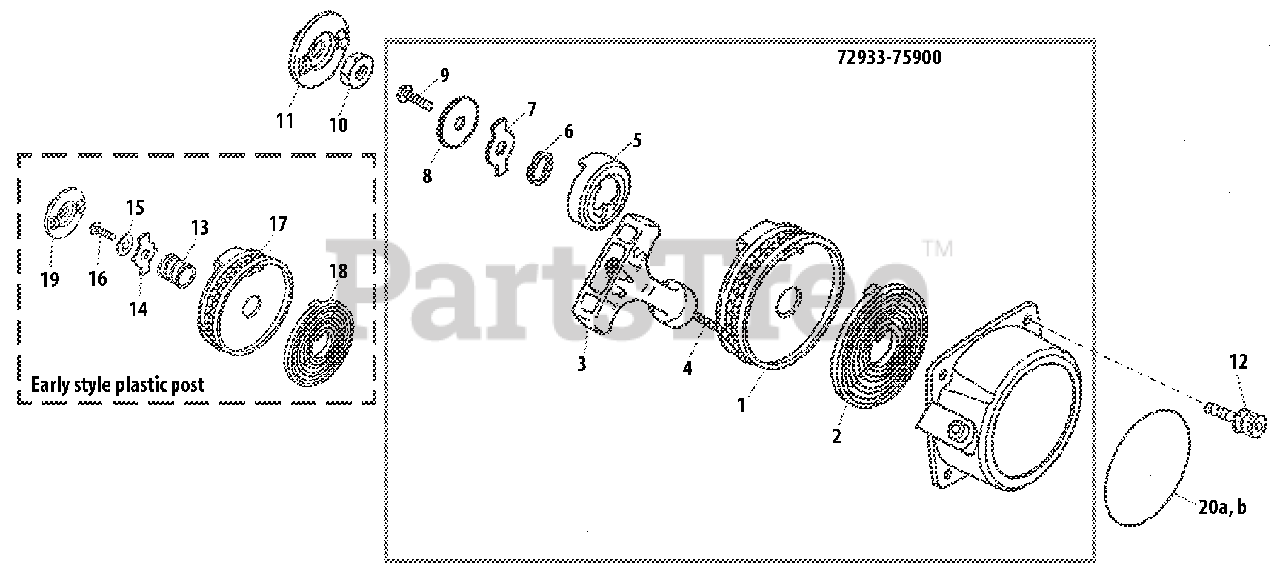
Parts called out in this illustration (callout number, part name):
1	REEL, ROPE
2	SPRING, RECOIL
3	GRIP, STARTER
4	ROPE, STARTER
5	RATCHET
6	WASHER, WAVE
7	RETAINER
8	WASHER 5 MM
9	SCREW 5 MM
10	NUT M8×1
11	PULLEY, STARTER
12	BOLT M4×12
13	SPRING, COMPRESSION
14	RETAINER
15	WASHER
17	REEL
18	SPRING, RECOIL
19	PULLEY, STARTER
20	LABEL, RECOIL STARTER
20	LABEL
72933-75900	STARTER ASSY, RECOIL
